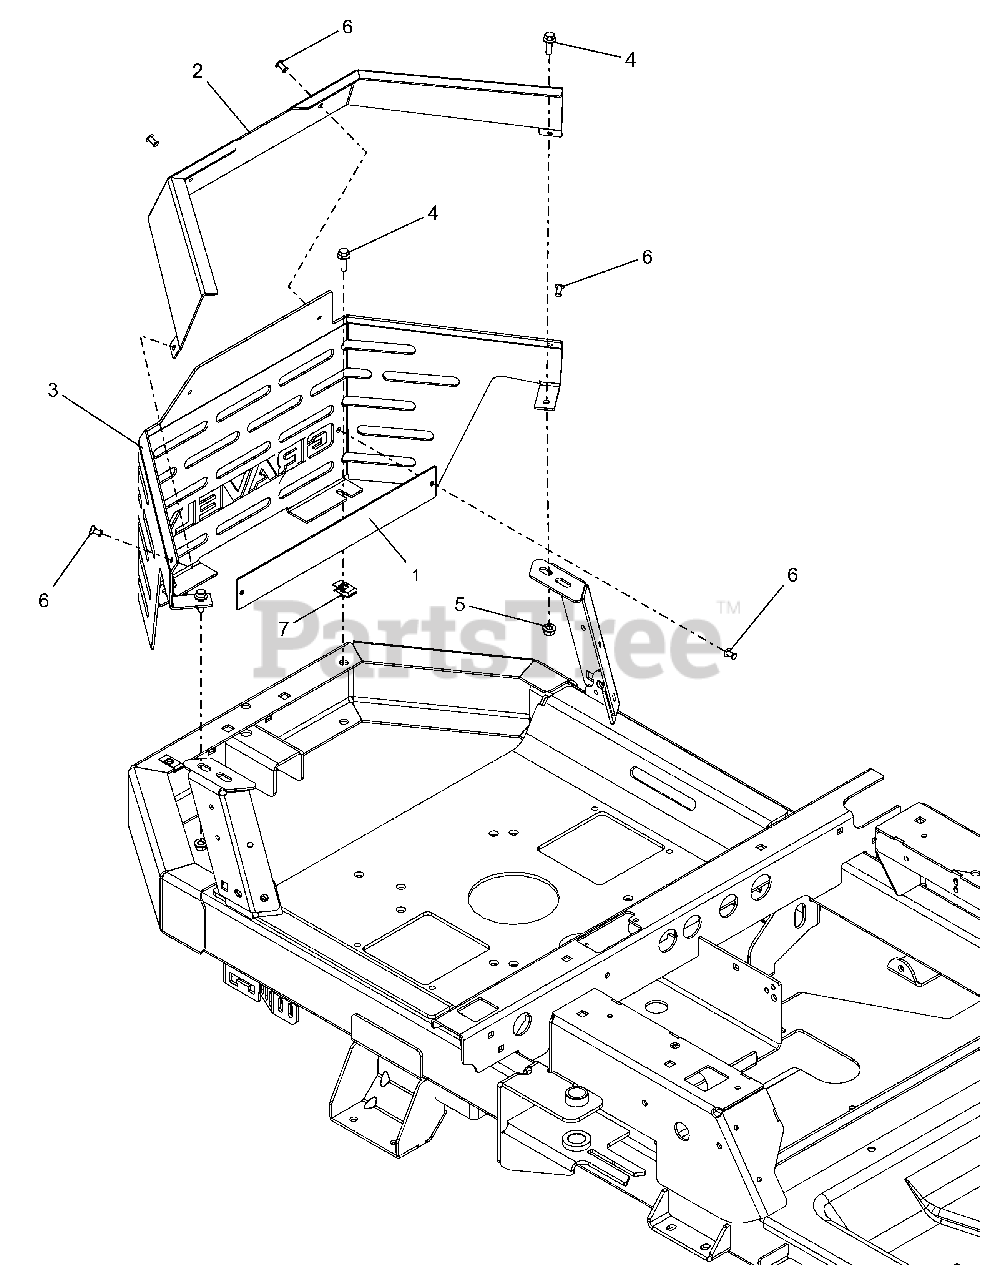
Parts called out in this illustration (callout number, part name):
1	PLATE, SHROUD BACKER
2	WLDMT, ENGINE SHROUD TRIM-XL
3	SHROUD, ENGINE - GRAVELY XL
4	BLT,HEX-FLG .25-20X.75 G5 BFP
5	@NUT-LK-TOP-FLG .25-20 YWZC
6	RIVET, #66 STEEL POP PD BLACK
7	NUT-RTNR .25-20X.56
